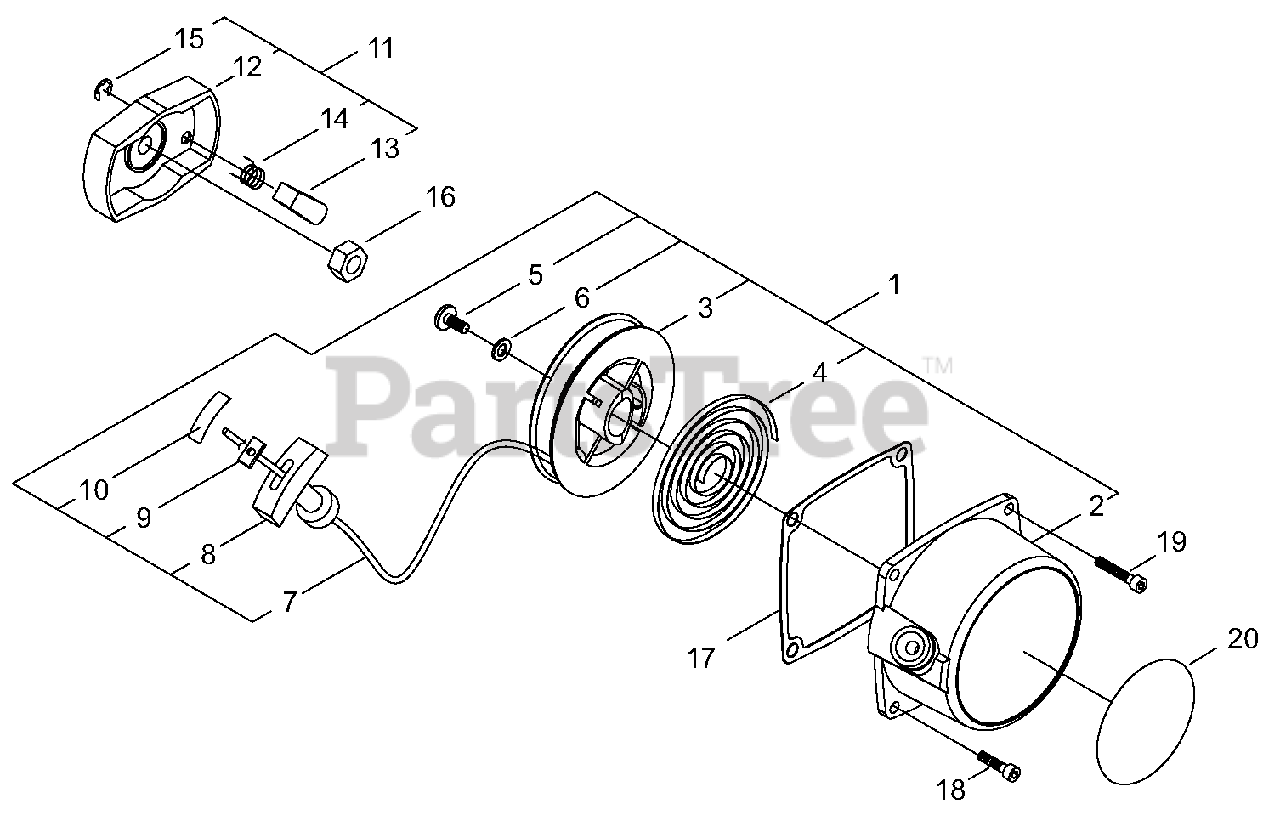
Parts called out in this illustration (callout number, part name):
1	STARTER ASSY, RECOIL
2	CASE, RECOIL STARTER
3	REEL, ROPE
4	SPRING, RECOIL
5	SCREW 5
6	WASHER
7	ROPE, STARTER
8	GRIP, STARTER
9	RETAINER, ROPE
10	TAPE
11	PULLEY ASSY, STARTER
12	PULLEY, STARTER
13	PAWL, STARTER
14	SPRING, RETURN
15	E-RING 4
16	NUT M8×H5
17	GASKET, RECOIL STARTER
18	BOLT M4×16
19	BOLT M4×20
20	LABEL, TRADE
